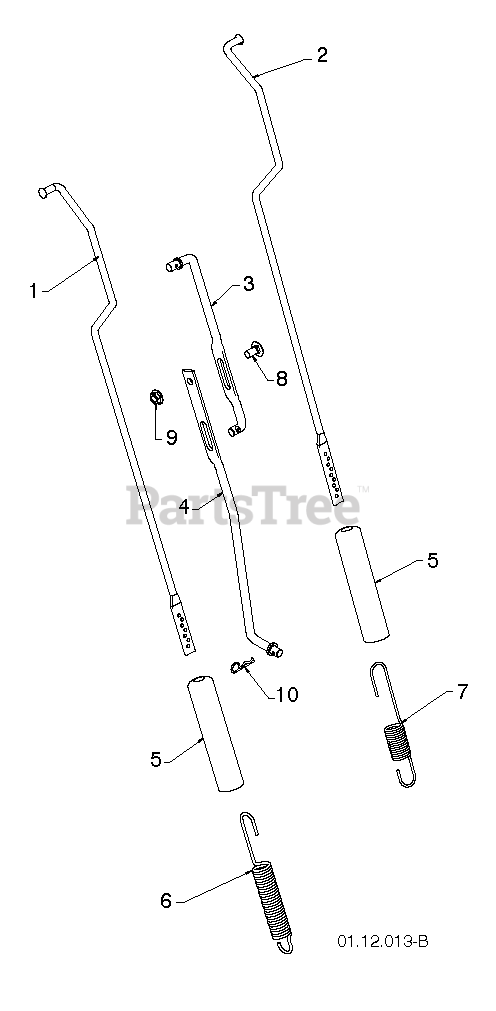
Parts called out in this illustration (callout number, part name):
1	ROD.IMPELLER
2	ROD.TRACTION
3	ROD, UPPER SPEED CONTROL
4	ROD, LOWER SPEED CONTROL.SNOW
5	SLEEVE, SPRING
6	SPRING.CONTROL.ROD.SNOW
7	SPRING.TRACTION.ROD.SNOW
8	BOLT
9	NUT.FLANGE.5/16
10	SPRING RETAINER
